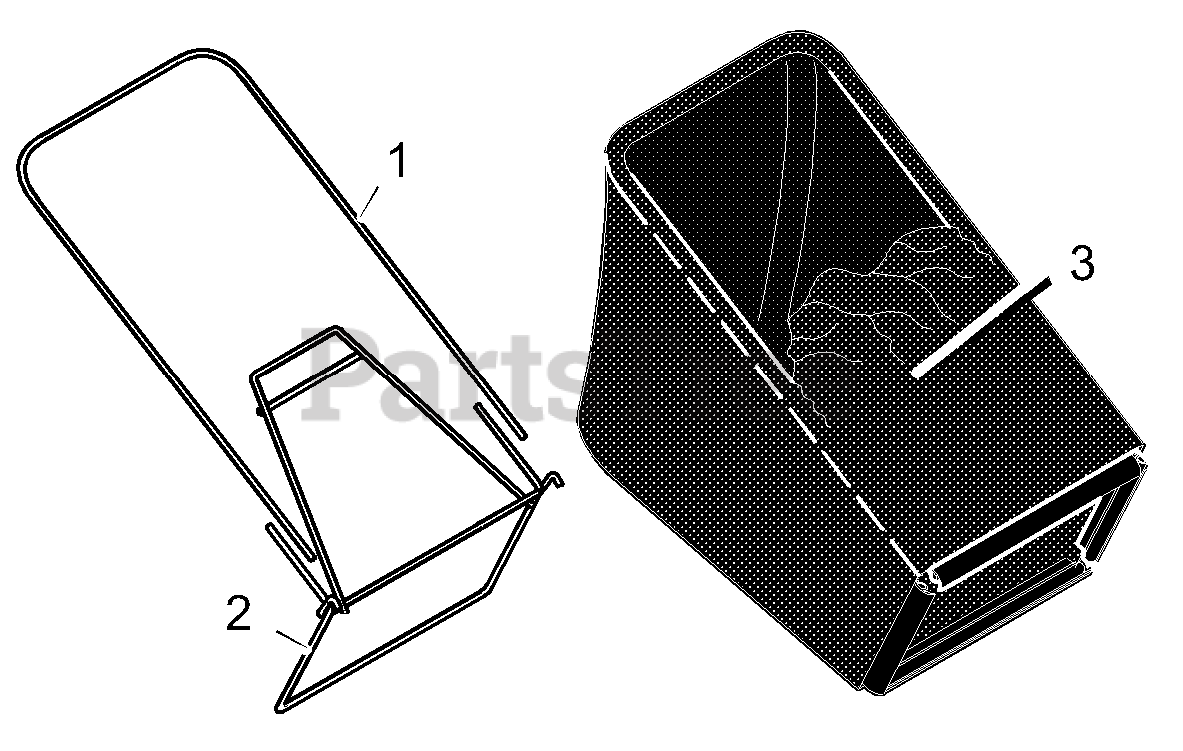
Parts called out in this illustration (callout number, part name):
1	Frame, Top
2	Frame Assy.
3	Bag, Cloth
